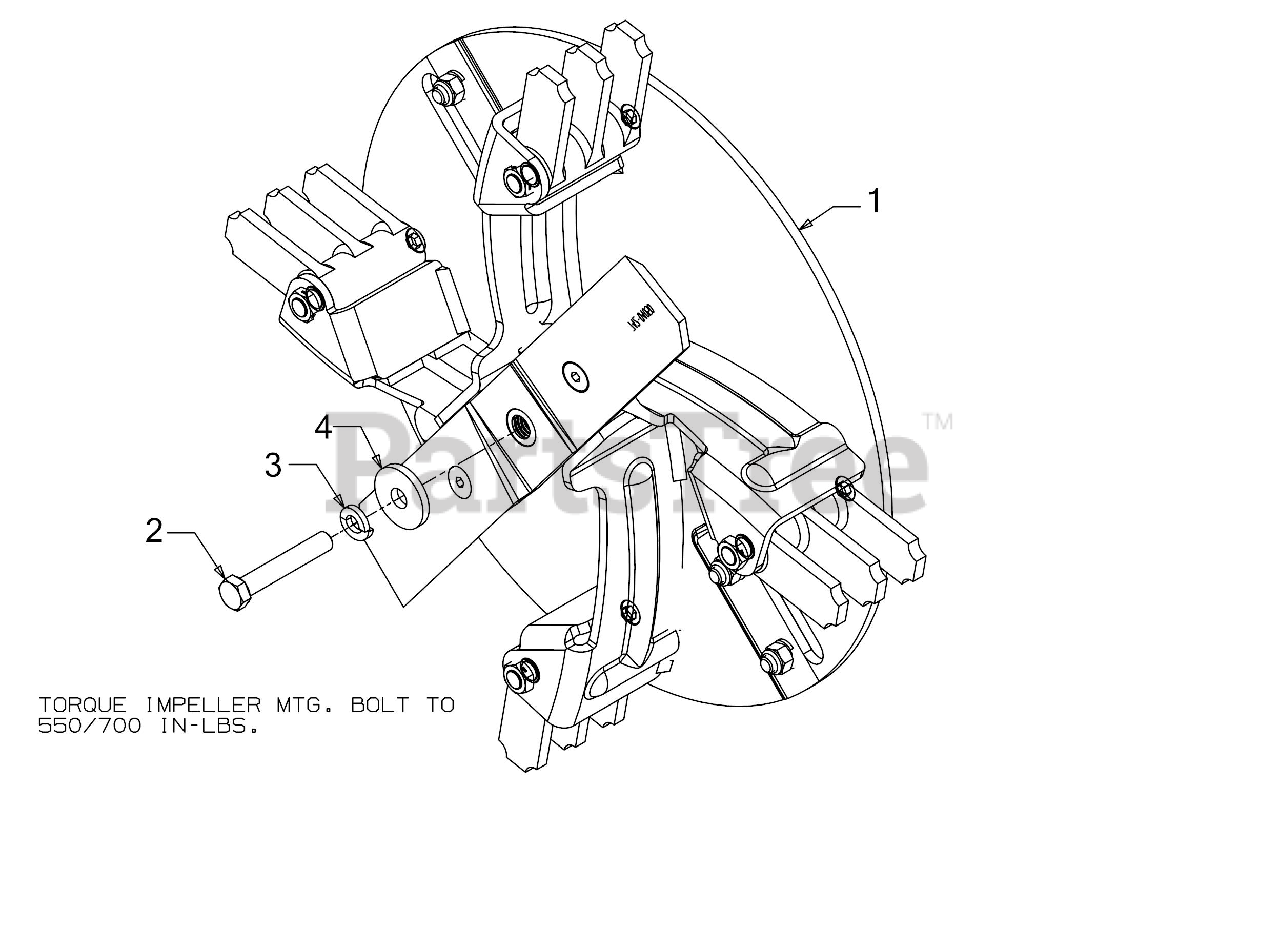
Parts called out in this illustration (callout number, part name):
1	IMPELLER ASSEMBLY
2	SCREW 3/8-24X2.25 GR8
3	LOCK WASHER 3/8HD
4	FLAT WASHER
